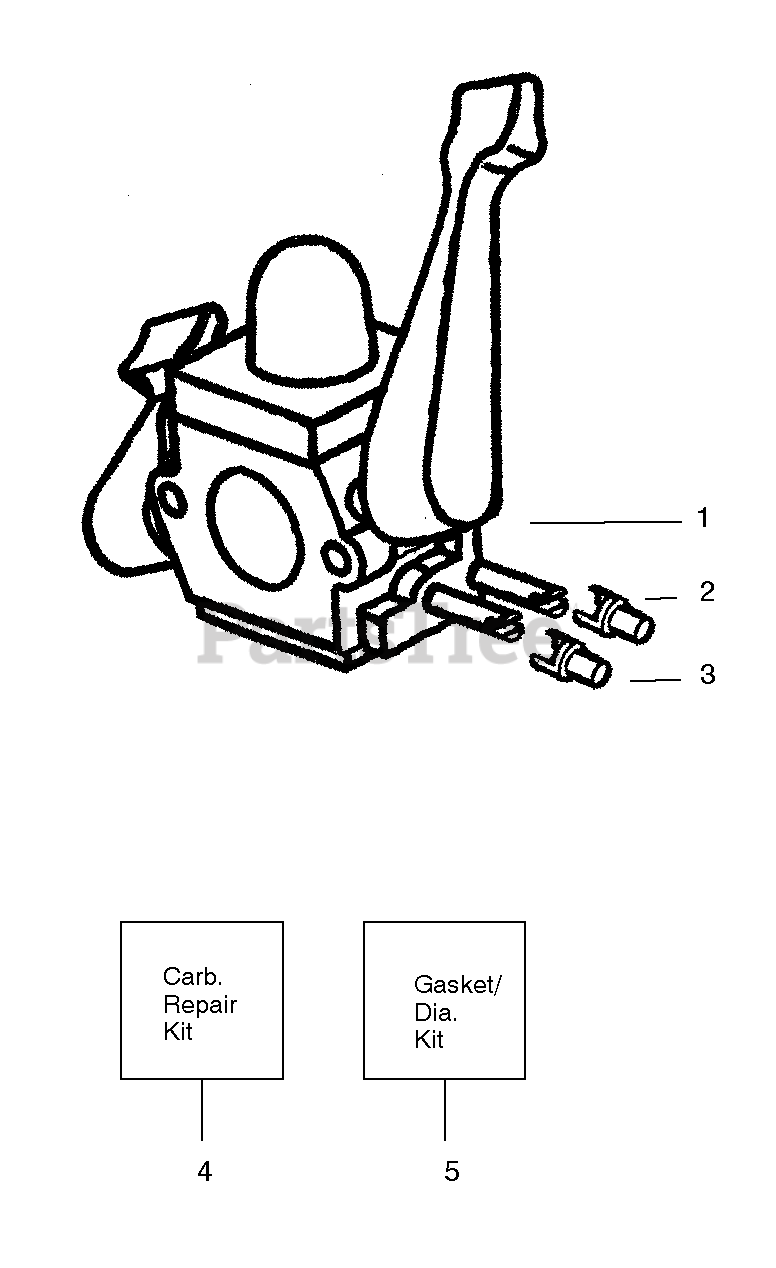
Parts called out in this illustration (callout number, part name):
1	Assy-Carb. Zama (C1Q-W11)
2	Cap-Limiter (high) brown
3	Cap-Limiter (low) tan
4	Kit-Carb. Repair
5	Kit-Dia. (GND-34)
